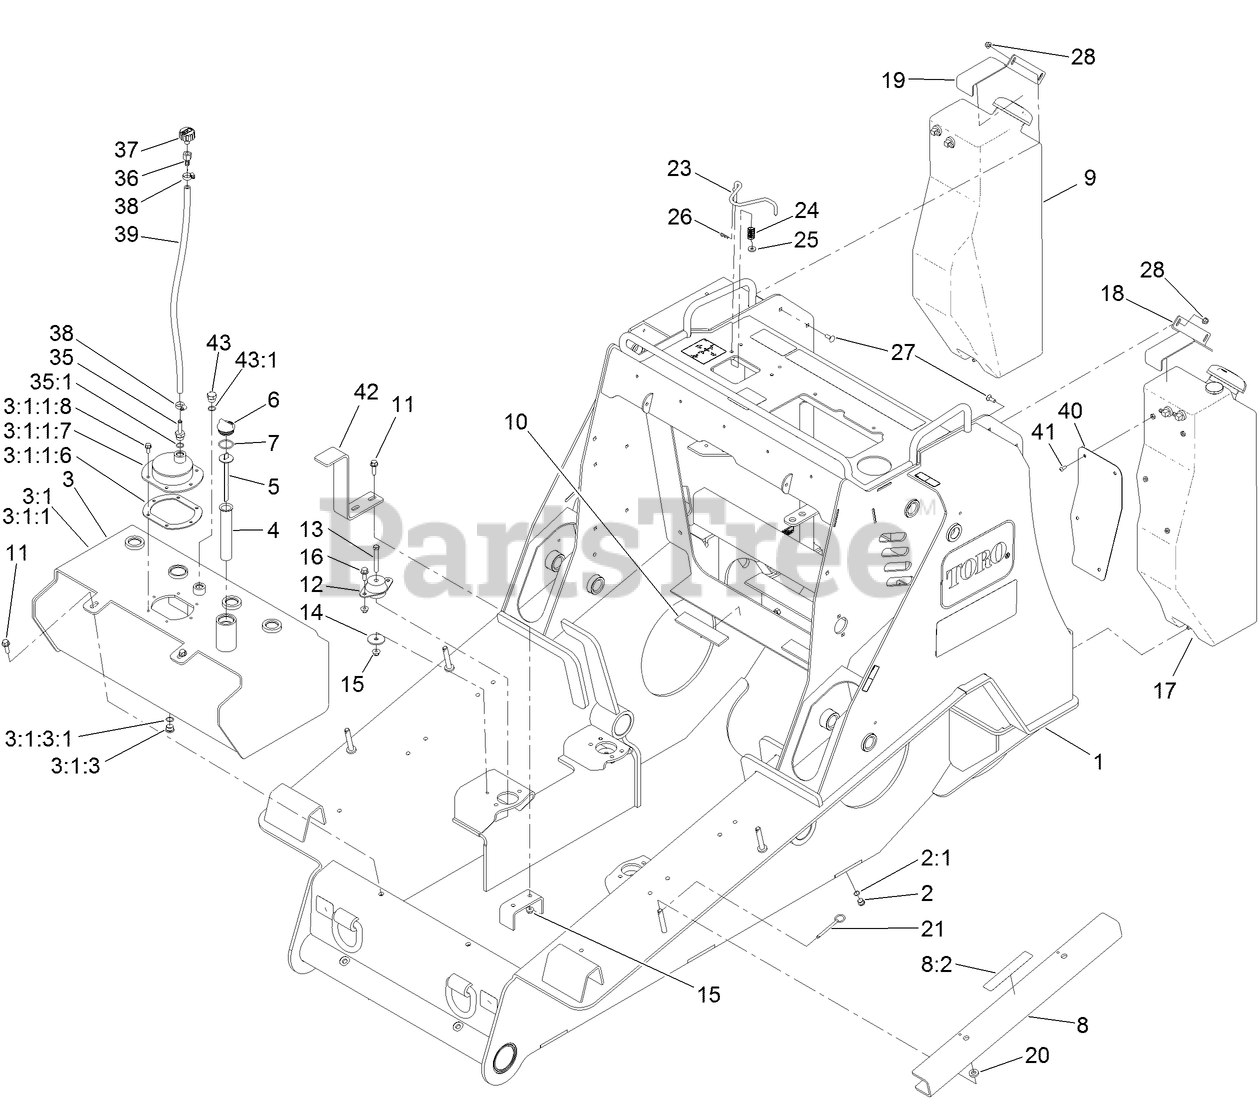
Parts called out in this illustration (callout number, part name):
1	FRAME ASM
2	PLUG-HEX, HOLLOW
2:1	O-RING
3	HYD TANK ASM
3:1	TANK-HYD
3:1:1	TANK-HYD, TOP
3:1:1:6	GASKET-COVER, ACCESS
3:1:1:7	COVER-ACCESS
3:1:1:8	SCREW-HHF
3:1:3	PLUG-HEX
3:1:3:1	O-RING
4	FILTER-SCREEN
5	DIPSTICK
6	PLUG-PLASTIC
7	O-RING
8	ARM-LOCKING
8:2	DECAL-DANGER
9	RH FUEL TANK ASM
10	PAD-RUBBER
11	SCREW-HHF
12	MOUNT-ENGINE
13	SCREW-HH
14	WASHER-REBOUND
15	NUT-HF, NI
16	SCREW-HHF
17	LH FUEL TANK ASM
18	BRACKET-TANK, LH
19	BRACKET-TANK, RH
20	WASHER-NEOPRENE
21	PIN-RING
23	ROD-INTERLOCK
24	SPRING-CONTROL
25	WASHER-FLAT
27	SCREW-CARR
28	NUT-HF, NI
35	FITTING-STR
35:1	O-RING
36	FITTING-FEMALE, BARBED
37	BREATHER
38	CLAMP-HOSE
39	HOSE-FUEL
40	PLATE-GUARD, TANK
41	SCREW-HSBH
42	STRAP-HOLD DOWN
43	PLUG-HYD, HH
43:1	O-RING
